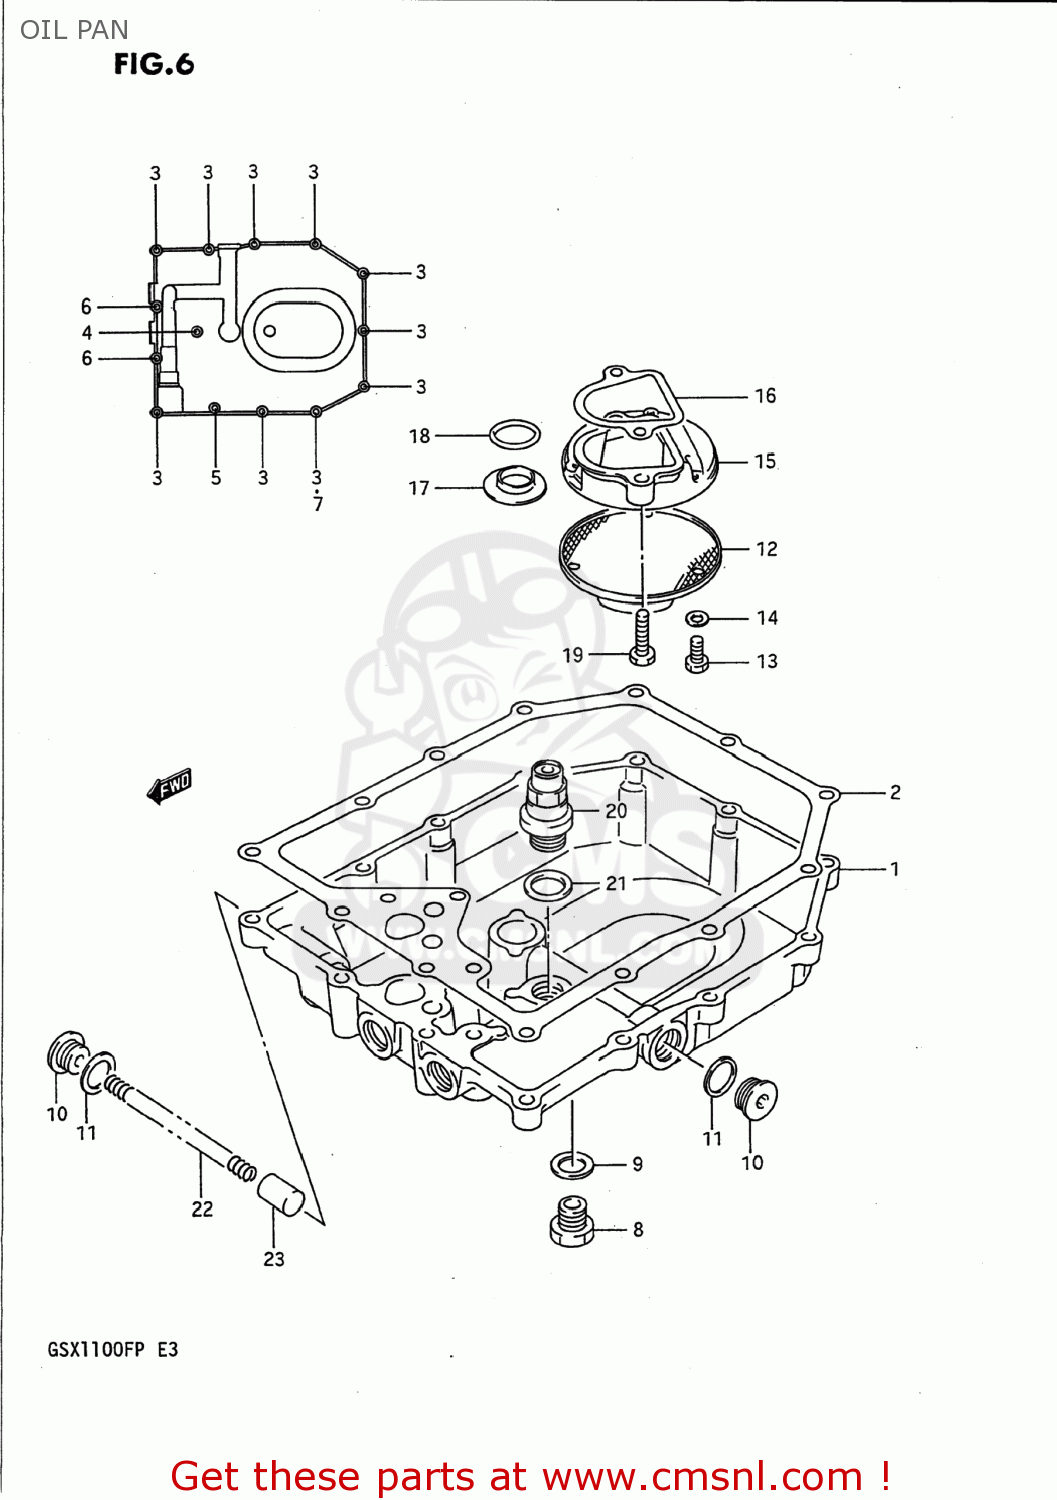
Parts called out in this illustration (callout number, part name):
1	PAN,OIL
2	GASKET,OIL PAN (NAS)
3	BOLT
4	BOLT
5	BOLT
6	BOLT
7	GASKET(5.8X11X1.2) (NAS)
8	PLUG
9	GASKET(14X19.2X2) (NAS)
10	PLUG
11	GASKET(16X22X2) (NAS)
12	STRAINER,ENGINE OIL
13	BOLT
14	WASHER,LOCK
15	PROTECTOR,OIL STRAINER
16	GASKET,OIL STRAINER PROTECTOR (NAS)
17	GASKET,OIL OUTLET (NAS)
18	O RING(D:3.2,ID:17.8)
19	BOLT 6X25
20	VALVE ASSEMBLY,OIL RELIEF
21	GASKET(16X22X2) (NAS)
22	SPRING
23	PLUNGER,OIL CONTROLL
